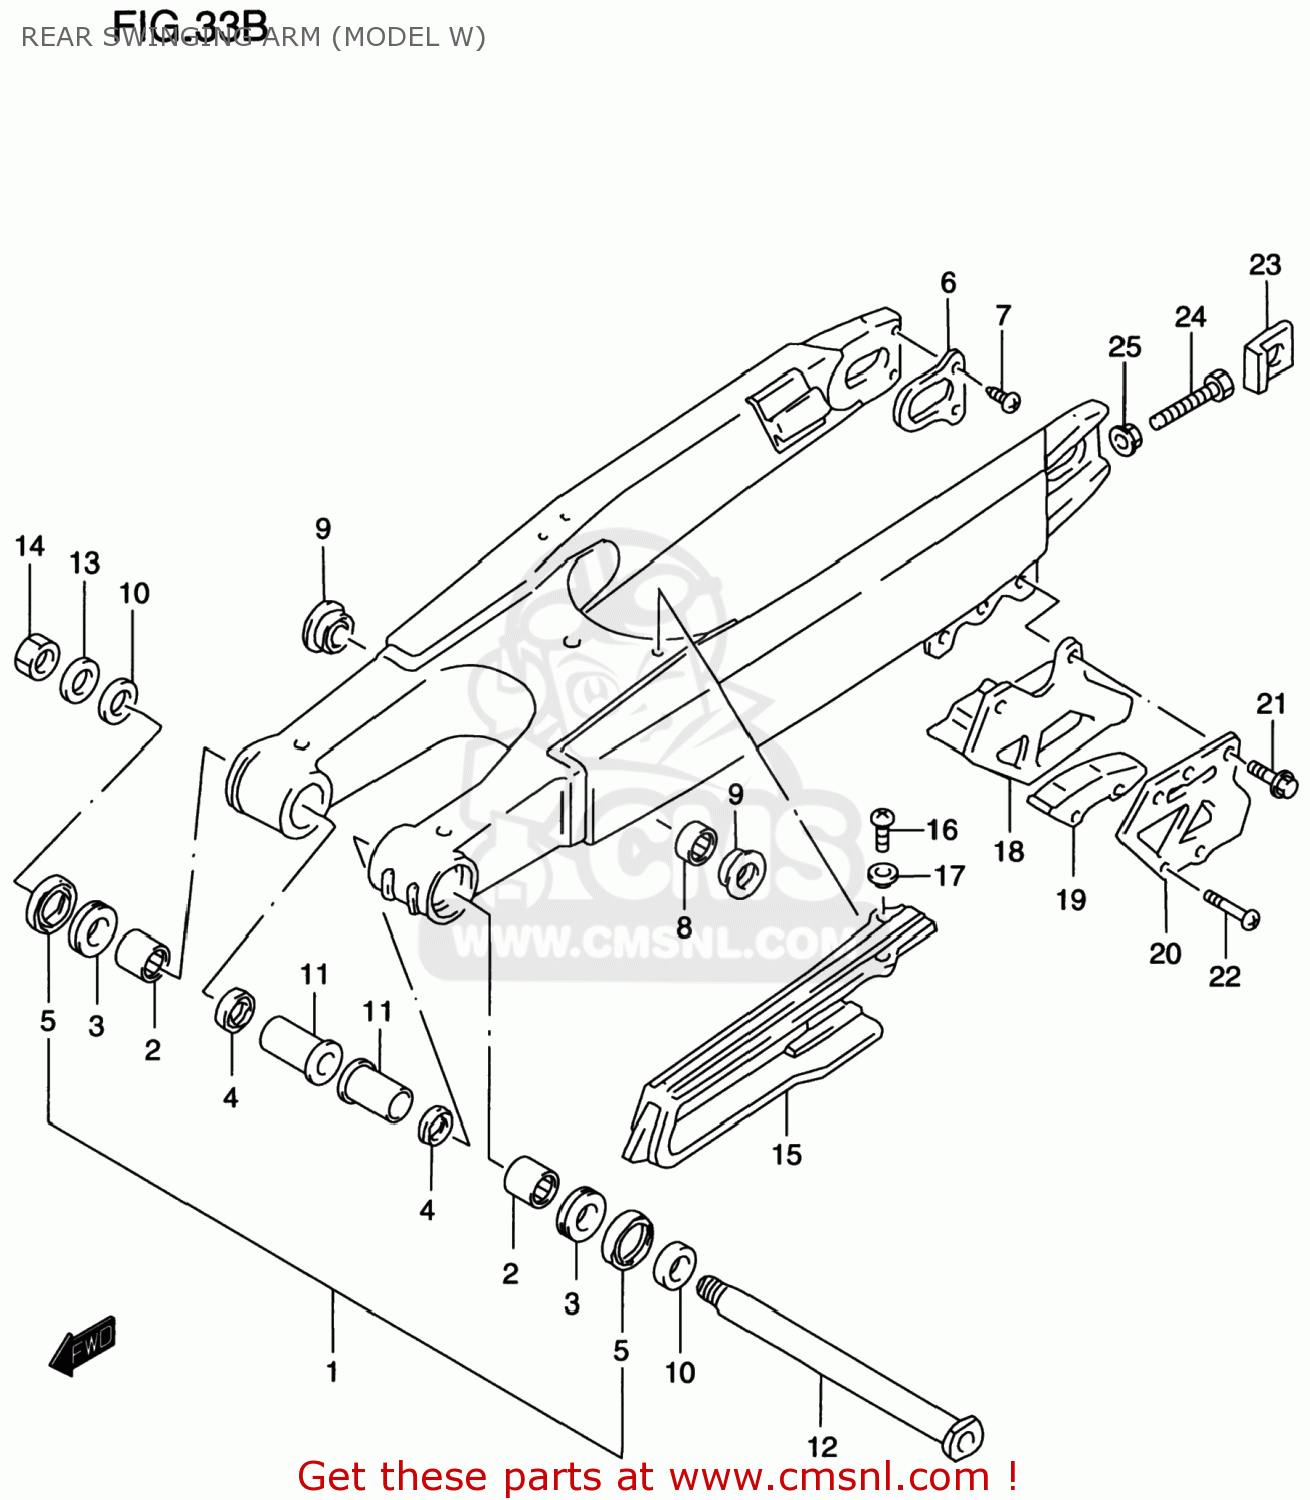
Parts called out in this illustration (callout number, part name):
1	SWING ARM ASSEMBLY,REAR
2	BEARING(22X29X30)
3	BEARING(22X35X2)
4	SEAL,OIL(22X29X4)
5	SEAL,RR SWGARM PIVOT OUTER
6	PLATE,SWING ARM RR
7	SCREW,UPPER
8	BEARING(22X28X16)
9	SEAL,SWINGING ARM RR
10	SPACER,RR SWGARM PIVOT OUTER
11	SPACER,SWGARM PIVOT INNER
12	SHAFT,RR SWINGINGARM PIVOT
13	WASHER, FIXED DRIVE FACE
14	NUT
15	BUFFER,CHAIN TOUCH DEFENSE
16	SCREW
17	WASHER
18	GUIDE,CHAIN
19	DEFENSE,CHAIN GUIDE
20	PLATE,CHAIN GUIDE OUTER
21	SCREW
22	SCREW(6X40)
23	WASHER,CHAIN ADJUSTER
24	BOLT(8X50)
25	NUT
